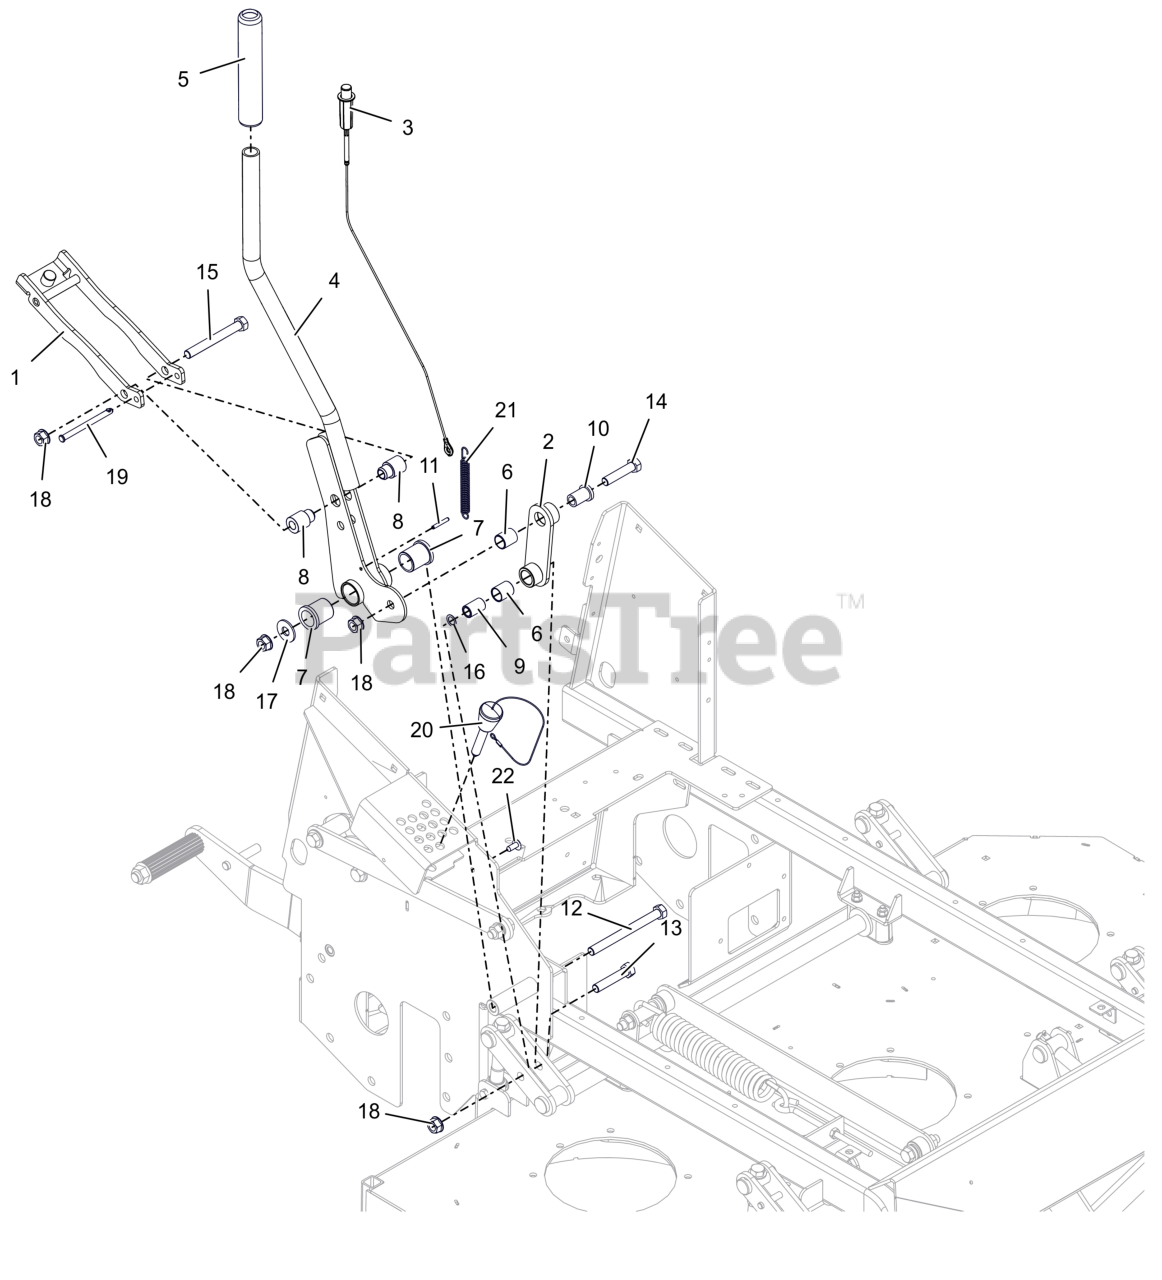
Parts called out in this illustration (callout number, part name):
1	WLDMT, HOC BRACKET (BLACK)
2	WLDMT, HOC LEVER LINK (BLACK)
3	CABLE, HOC PUSH CONTROL
4	WLDMT, HOC LEVER (BLACK)
5	GRIP, DECK LIFT
6	BRG- .750 X .875 X 1.000
7	BSHG-FLG 1.00X1.25X1.50X1.50
8	BSHG-FLG.515X.750X1.544X1.000
9	SPCR, SLV .532 X .750 X 1.150
10	BSHG-FLG .515X.746X1.290X1.000
11	PIN-ROLL .188X1.25
12	BLT,HEX .50-13X5.50 G5 ZCC
13	BLT, HEX .50-13X2.50 G5 ZCC
14	BLT, HEX .50-13X2.25 G5 ZCC
15	BLT, HEX .50-13X4.25 G5 ZCC
16	WASHER, .500X.750X.020 THRUST
17	WSHR,FLT .563X1.375X.109 ZCC
18	NUT-LK-CTR-FLG .500-13 GG ZCC
19	PIN-SLIC .3125 X 4.015 X 3.625
20	PIN- MAGNETIC .50X2.70
21	SPRING,EXT,.061X.50X3.0
22	XMAS TREE FASTNER-BLACK
